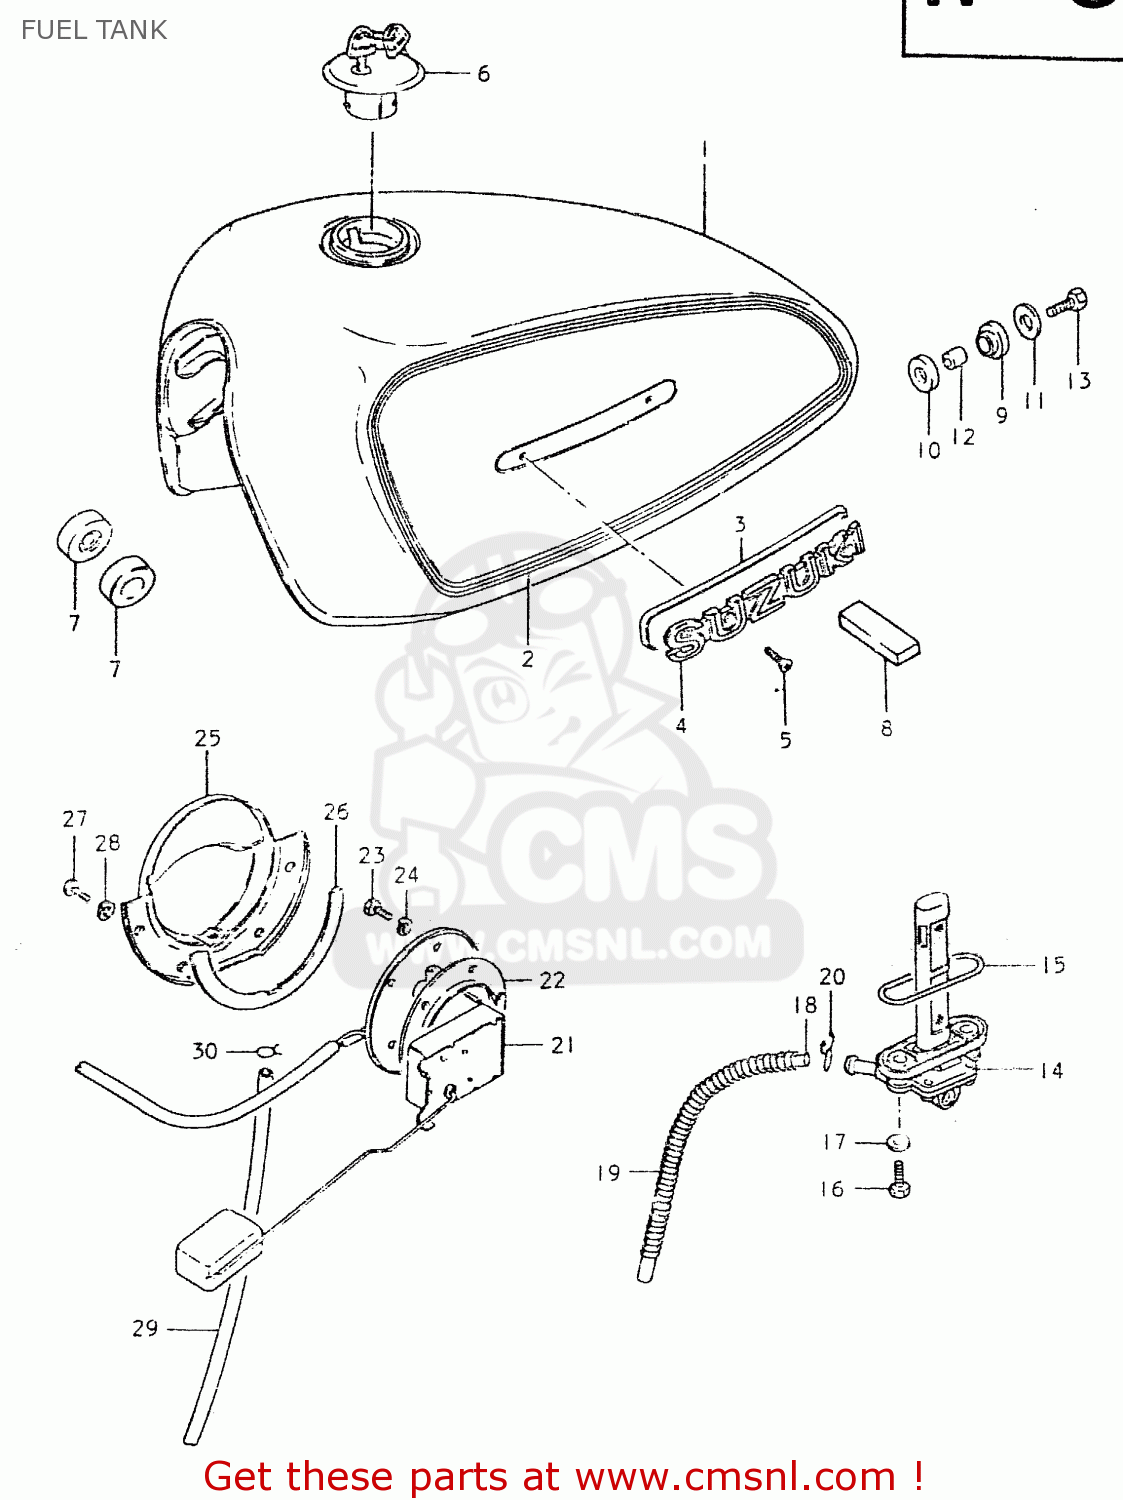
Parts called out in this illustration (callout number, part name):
1	TANK ASSEMBLY,FUEL
2	TAPE SET,FUEL TANK
3	CUSHION, EMBLEM
4	EMBLEM
5	SCREW 3X6
6	CAP SET,FUEL TANK
7	CUSHION
8	CUSHION
9	CUSHION
10	CUSHION
11	WASHER (8.5X29X1.6)
12	SPACER(8.5X12X19)
13	BOLT (8X30)
14	COCK ASSY,FUEL
15	GASKET (NAS)
16	SCREW (6X25)
17	GASKET
18	HOSE
19	SPRING
20	CLIP
21	GAUGE ASSEMBLY,FUEL LEVEL
22	GASKET,FUEL LEVEL GAUGE (NAS)
23	BOLT
24	LOCK WASHER
25	PLATE,FUEL DRAIN
26	GASKET,FUEL DRAIN PLATE (NAS)
27	SCREW
28	LOCK WASHER
29	HOSE,FUEL
30	CLIP
